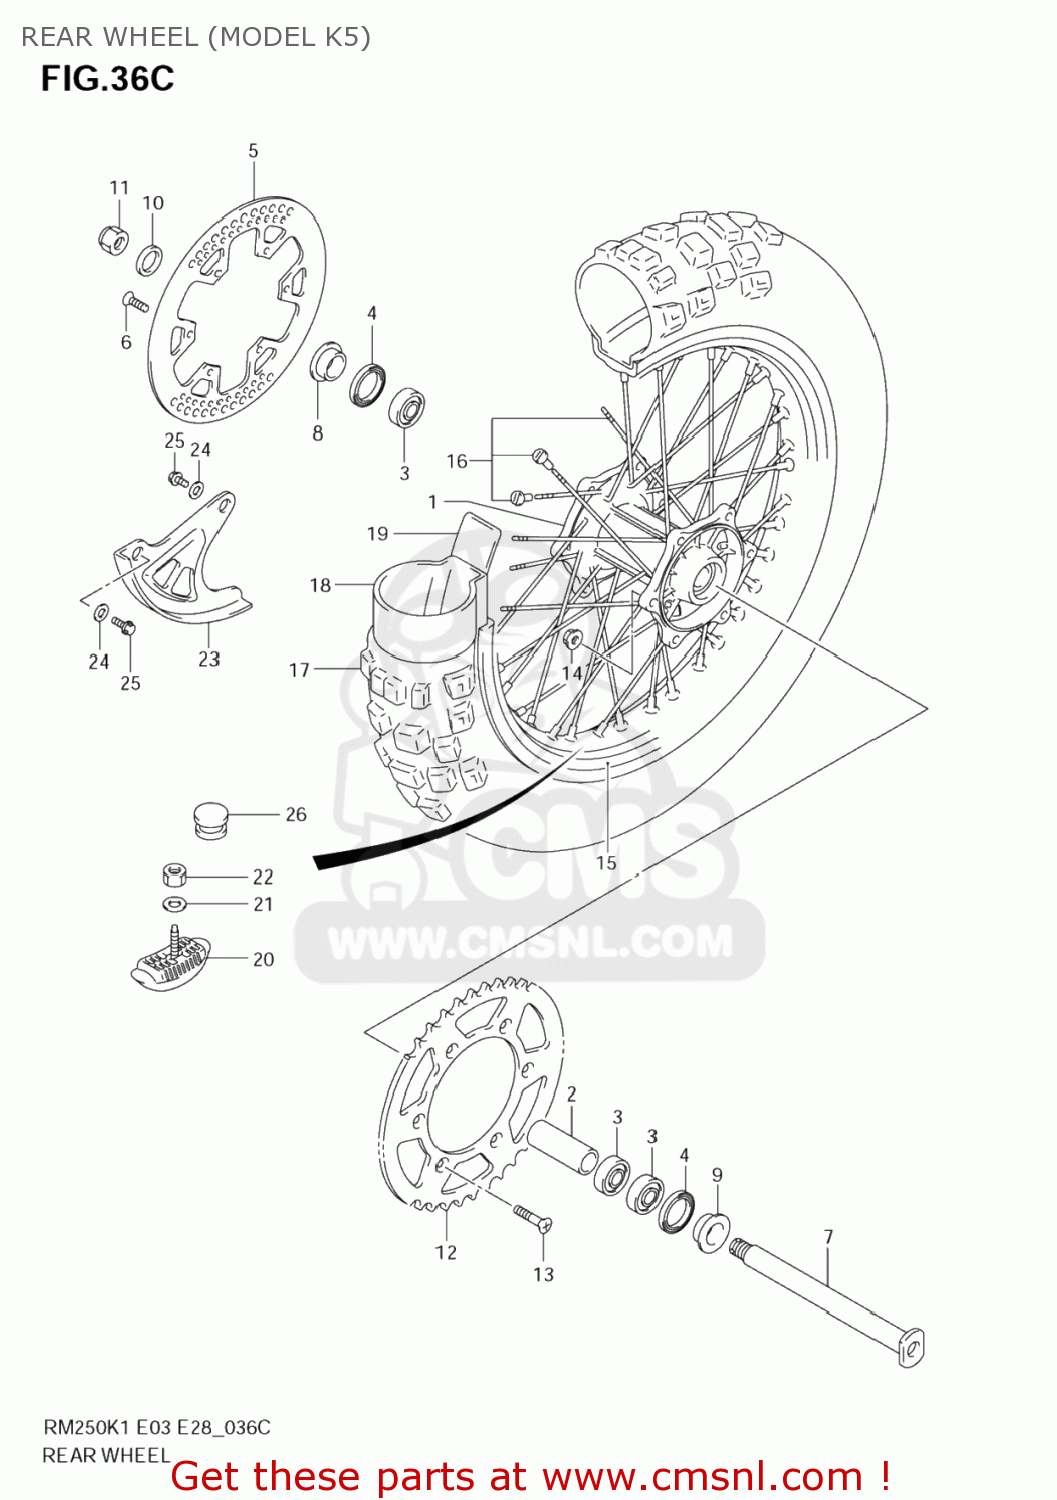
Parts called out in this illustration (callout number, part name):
1	HUB,RR WHEEL
2	SPACER,RR HUB BEARING
3	BEARING(22X44X12)
4	SEAL,OIL(30X44X7)
5	DISC,RR BRAKE
6	SCREW(6X18)
7	AXLE,RR
8	SPACER,RR AXLE
9	SPACER,RR AXLE
10	WASHER(19X32X3.2)
11	NUT
12	SPROCKET,RR(NT:50)
13	BOLT(8X28)
14	NUT
15	RIM,RR WHEEL(2.15X19 AL.)
16	SPOKE SET,RR WHEEL
17	TIRE,RR(110/90 19)
18	TUBE ASSY,WHEEL INNER
19	PROTECTOR,WHL INR TUBE
20	STOPPER,BEAD(2.15)
21	WASHER
22	NUT
23	COVER,REAR DIS
24	WASHER
25	BOLT(6X10)
26	CAP(OD:12)
